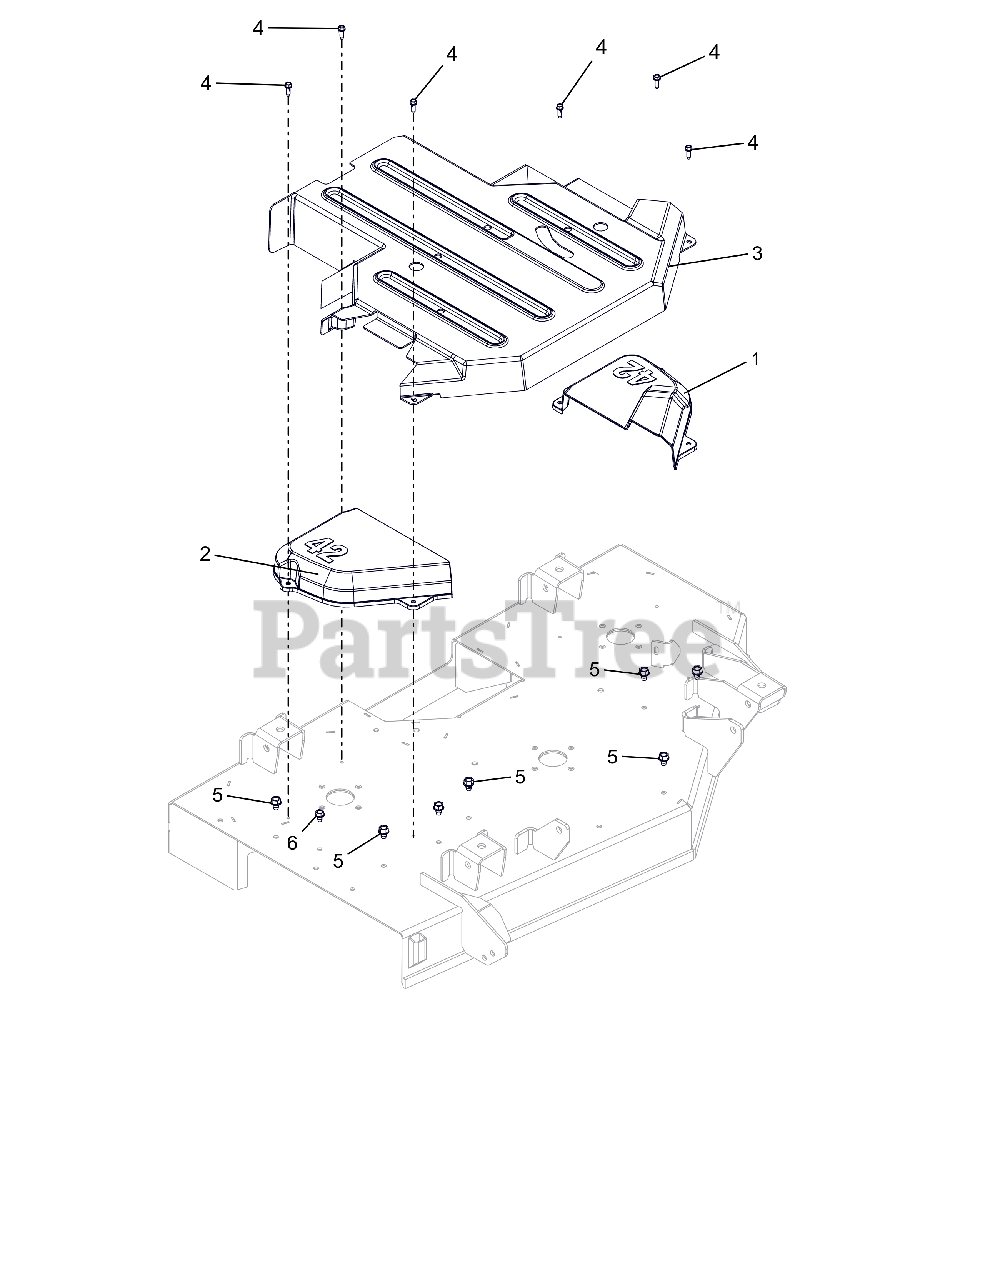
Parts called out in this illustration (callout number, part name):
1	COVER, BELT 42" LH
2	COVER, BELT 42" RH
3	GUARD, IKON BELT-42" CE
4	SCR,TAP .25-20X.75 HWH TR ZCC
5	SCR,TAP .375-16X.50 HWH TR ZCC
6	SCR,TAP .312-18X.50 HWH TR ZCC
